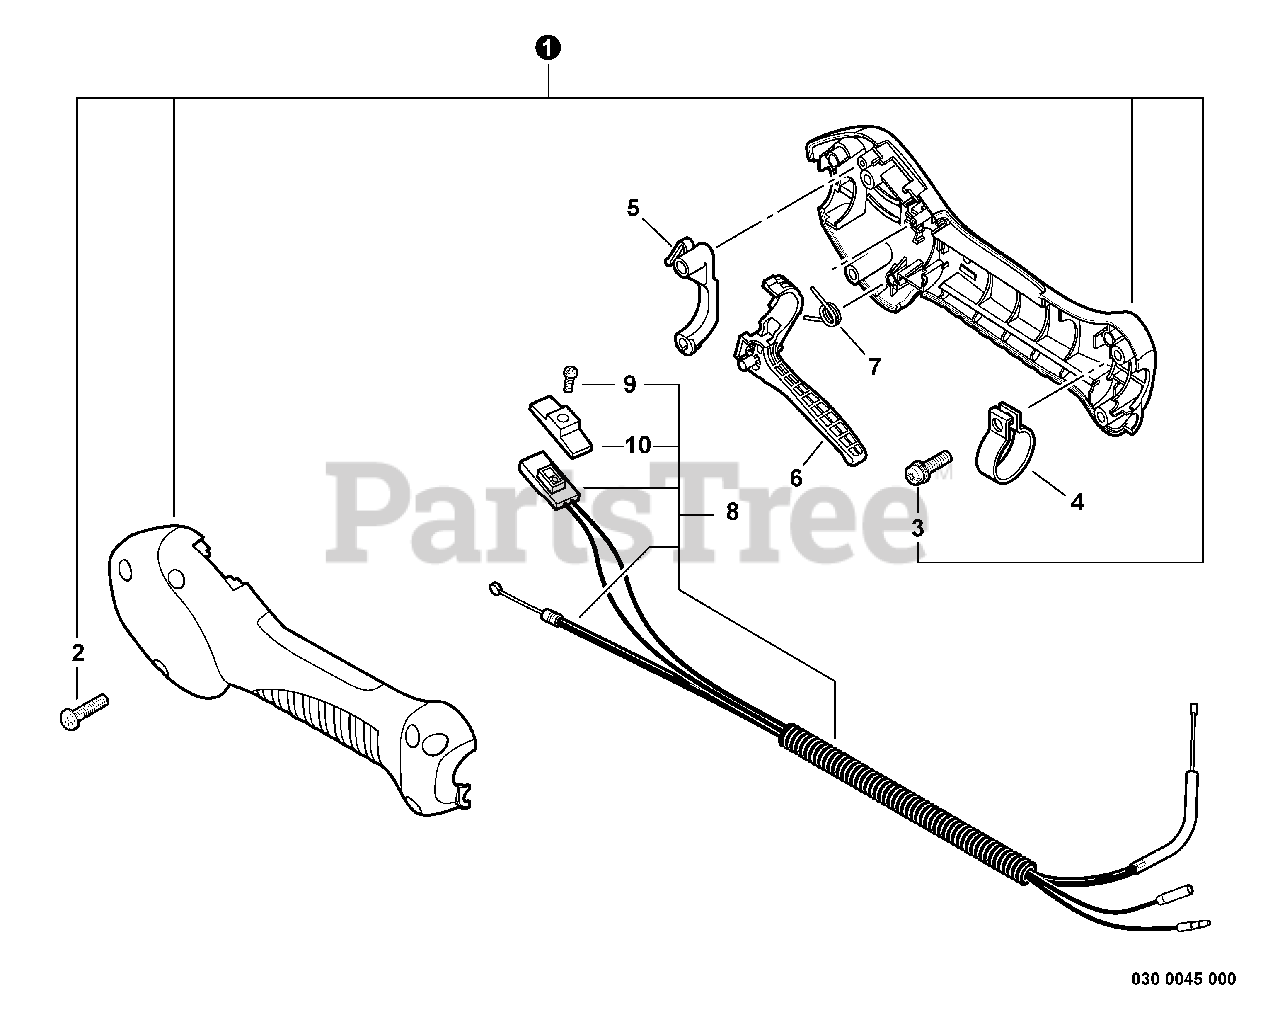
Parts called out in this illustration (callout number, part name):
1	CONTROL HANDLE KIT
3	SCREW 5×20
5	LOCKOUT, THROTTLE
6	TRIGGER, THROTTLE
7	SPRING, TORSION
8	CONTROL CABLE ASSY
9	SCREW 3×10
10	KNOB, SWITCH - ORANGE
